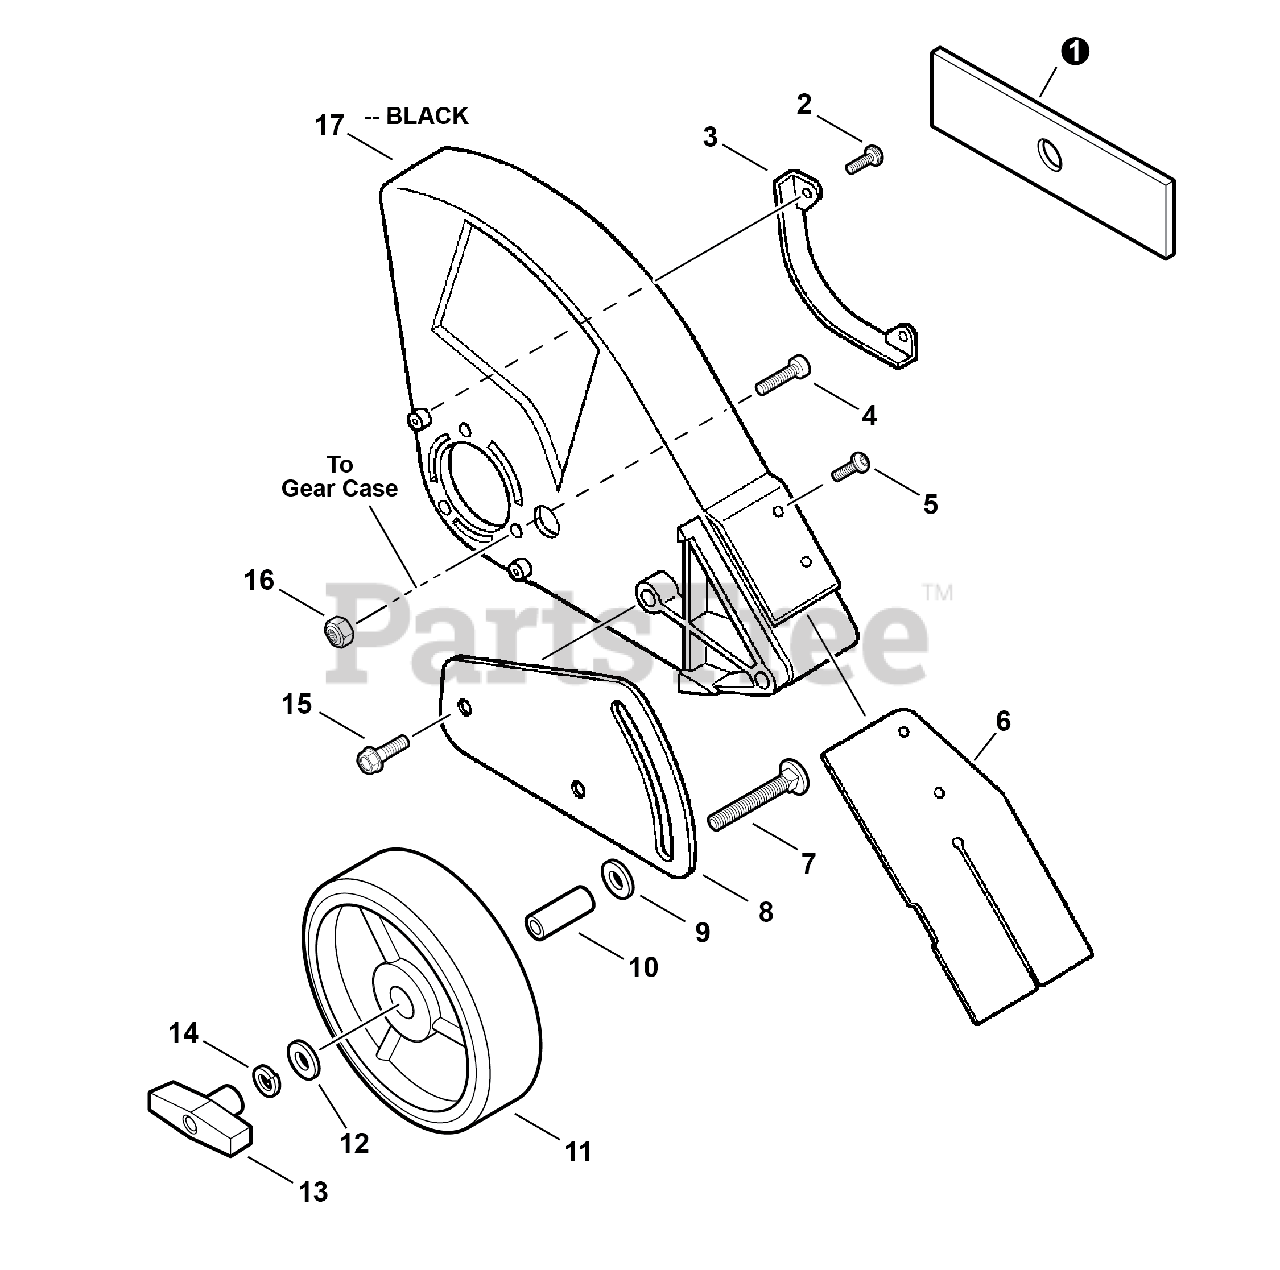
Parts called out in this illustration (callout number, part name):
1	BLADE, EDGER
2	SCREW - 4×16 -- TAPPING
4	SCREW - 5×20
5	SCREW - 4×20 -- TAPPING
6	FLAP, DEBRIS
7	BOLT - CARRIAGE
8	BRACKET, WHEEL
9	WASHER - 10
10	COLLAR - 12
11	WHEEL - 6×1.5
12	WASHER - 8
13	WINGNUT - 5/16-18
14	LOCKWASHER - 8
15	BOLT - 8
16	LOCKNUT - 5
17	SHIELD, BLADE
